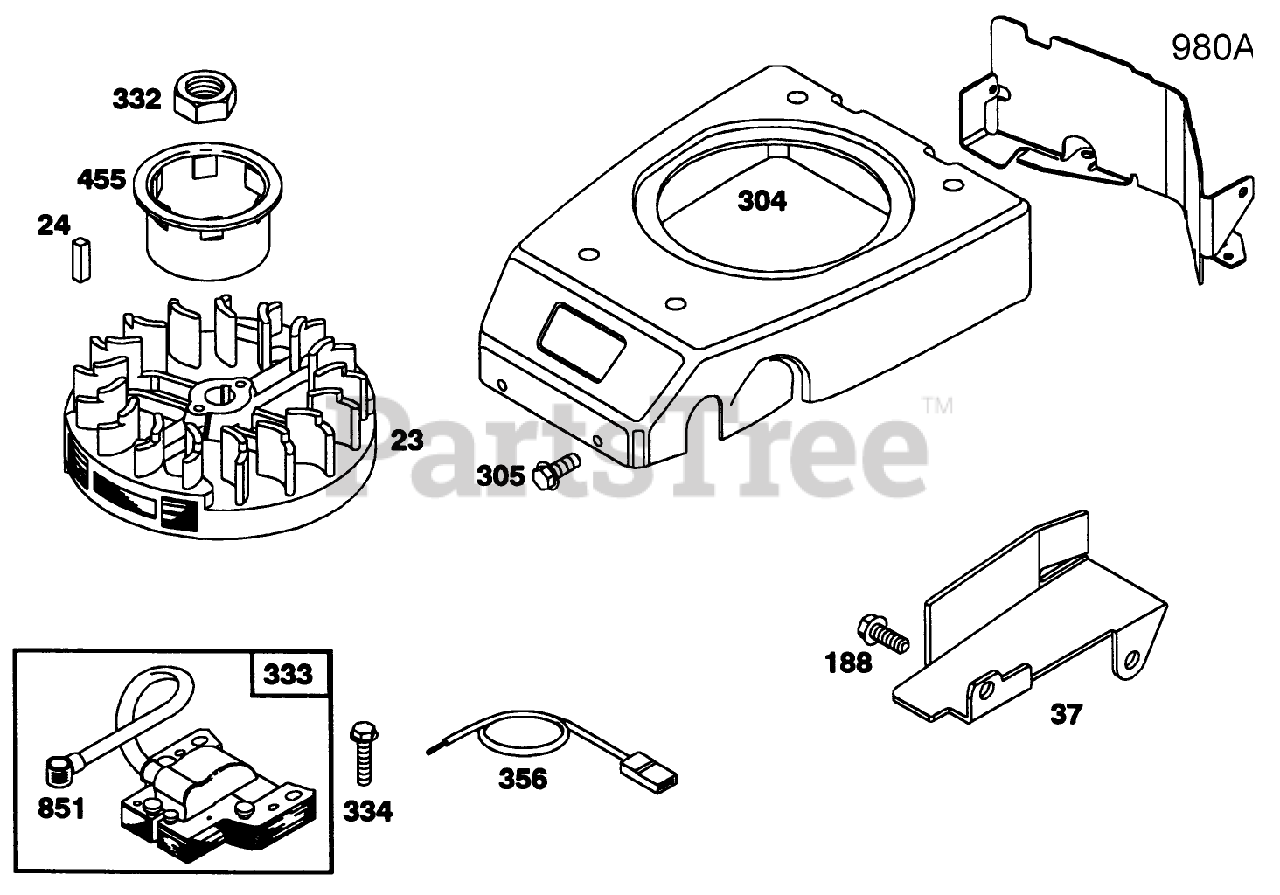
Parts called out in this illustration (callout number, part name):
24	KEY - FLYWHEEL
188	SCREW - SEM
304	BLOWER HSG ASM
305	SCREW - HEX HEAD
332	NUT - HEXAGON
356	WIRE - GROUND
980A	BLOWER HSG BRACKET
